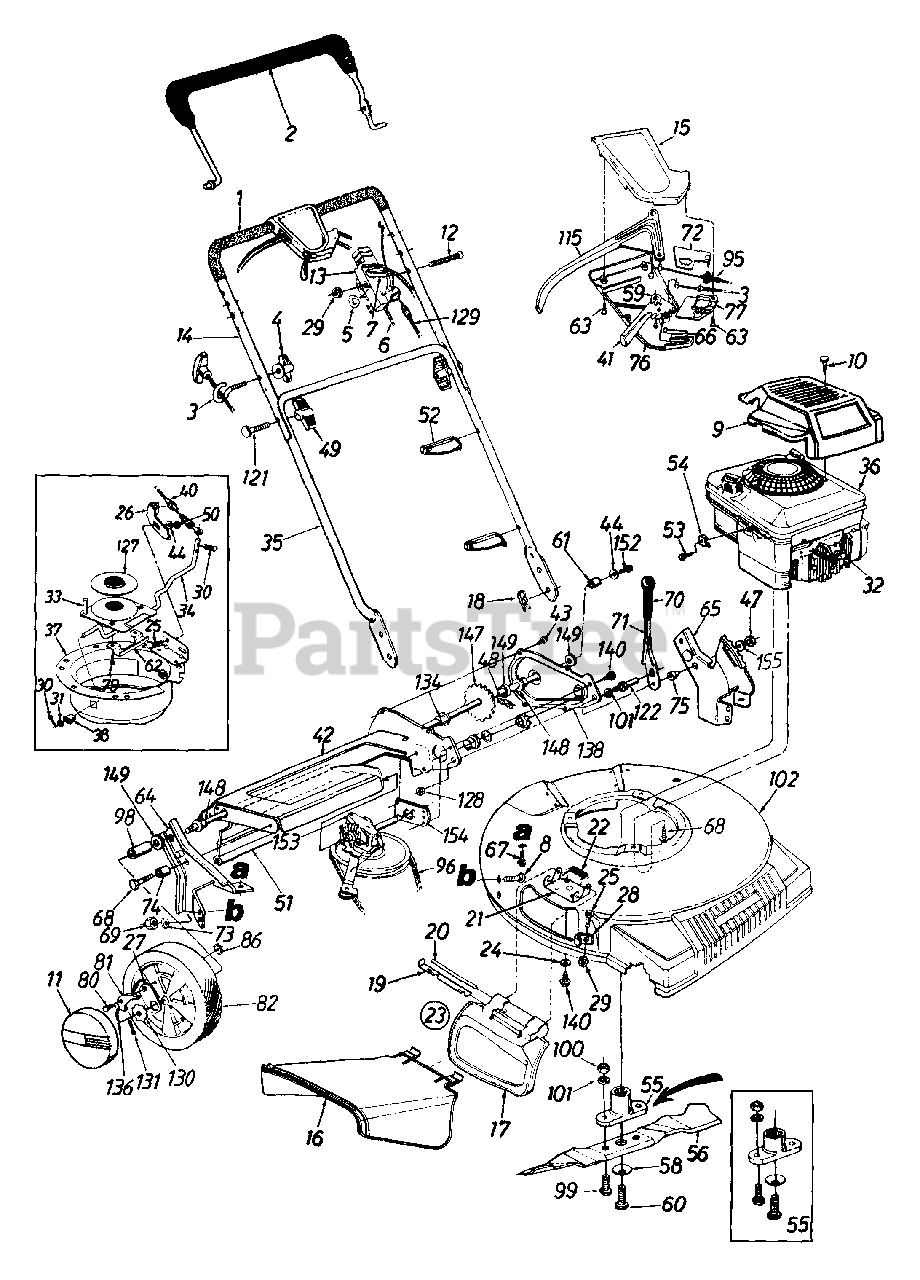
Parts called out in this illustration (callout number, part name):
1	Foam Grip
2	Control Handle
4	Handle Knob 1/4-20 Thd.
5	Curved Spring Wash. .66" I.D.
6	Throttle Wire - 55" Lg.
7	Throttle Lever
8	Carriage Bolt 5/16-18 x .62" Lg.
9	XTE Engine Shroud
10	Hi-Lo Screw #10 x 1.25" Lg.
11	Hub Cap
12	Oval C-Sunk Mach. Scr.
13	Throttle Body
15	Upper Control Housing
16	Side Chute Deflector
17	Mulch Plug
18	Internal Cotter Pin 5/16" Dia.
20	Hinge Pin
22	Torsion Spring
23	Mulch Plug Ass'y. Comp.
24	Bell-Wash. .265" I.D. x .75" O.D.
25	Carriage Bolt 1/4-20 x .5" Lg.
30	Cotter Pin 3/32" Dia. x .75"
31	Fl-Wash. .328" I.D. x .68"
32	Spark Plug Insulator
33	Lower Pulley Half Ass'y.
34	Shift Rod
36	Engine - 5.5 H.P.
40	6 Spd. Cable
41	6 Spd. Shift Lever
44	Bell-Wash. 1/4" I.D.
47	Hex Patch L-Nut 3/8-24 Thd.
48	#48 Chain .500" Pitch x 38 Links
49	Hand Knob
50	Hex L-Nut 1/4-20 Thd.
51	Rear Flap 4.8" x 17.5" Lg.
52	Cable Tie
53	Hex Wash. Hd. Scr. #10-32 x .62" Lg.
54	Casing Clamp
55	Blade Adapter Kit
56	21" Mulching Blade
58	Bell-Wash. .47" l.D. x 1.14" O.D.
59	Gear Insert
60	Hex Bolt 7/16-20 x 2.5"
61	Spacer .513" l.D.
67	Hex B-Tap Scr. 5/16-18
68	Hex TT-Tap Scr. 3/8-16
69	Hex Nut 5/16-18 Thd.
71	Height Adj. Lever
72	6 Spd. Rack Cable Brkt.
73	Bell-Wash. 5/16" I.D.
74	Spacer .383" I.D.
75	Shld. Spacer .5" Dia.
76	Lower Control Housing
77	Cable Mounting Cap
79	Hex Wash. Hd. Tap Scr. 1/4-20 x .38" Lg.
80	Shld. Scr..342" Dia. x .268
81	Pawl
82	Wheel Ass'y. Comp.
86	Weld Top L-Nut 1/4-20 Thd.
95	S.P. Cable
96	"V" - Belt
98	Sleeve .526" I.D.
99	Hex Bolt 3/8-24 x 1.0" Lg.
100	Hex Nut 3/8-24 Thd.
101	L-Wash. 3/8" I.D.
121	Curved Hd. Bolt 5/16-18 x 2" Lg.
122	Shld. Pin 1.43" Lg.
127	Pulley Half - Serrated
128	Hex Jam Nut 3/8-24 Thd.
129	Control Cable - 39"
130	Ratchet Wheel 1.62" O.D.
131	Cotter Pin 1/8" Dia. x 1"
134	Hex Flange Bearing
136	Spring - Nylon
147	Rear Shaft Ass'y. 21.44" Lg.
148	Hex Flange Brg. .506" I.D.
149	Fl-Wash. .531" I.D. x .930"
152	Hex Bolt 1/4-20 x .62" Lg. (Gr. 5)
153	Transmission Comp.
155	Fl-Wash. .385" I.D. x .87" O.D.
